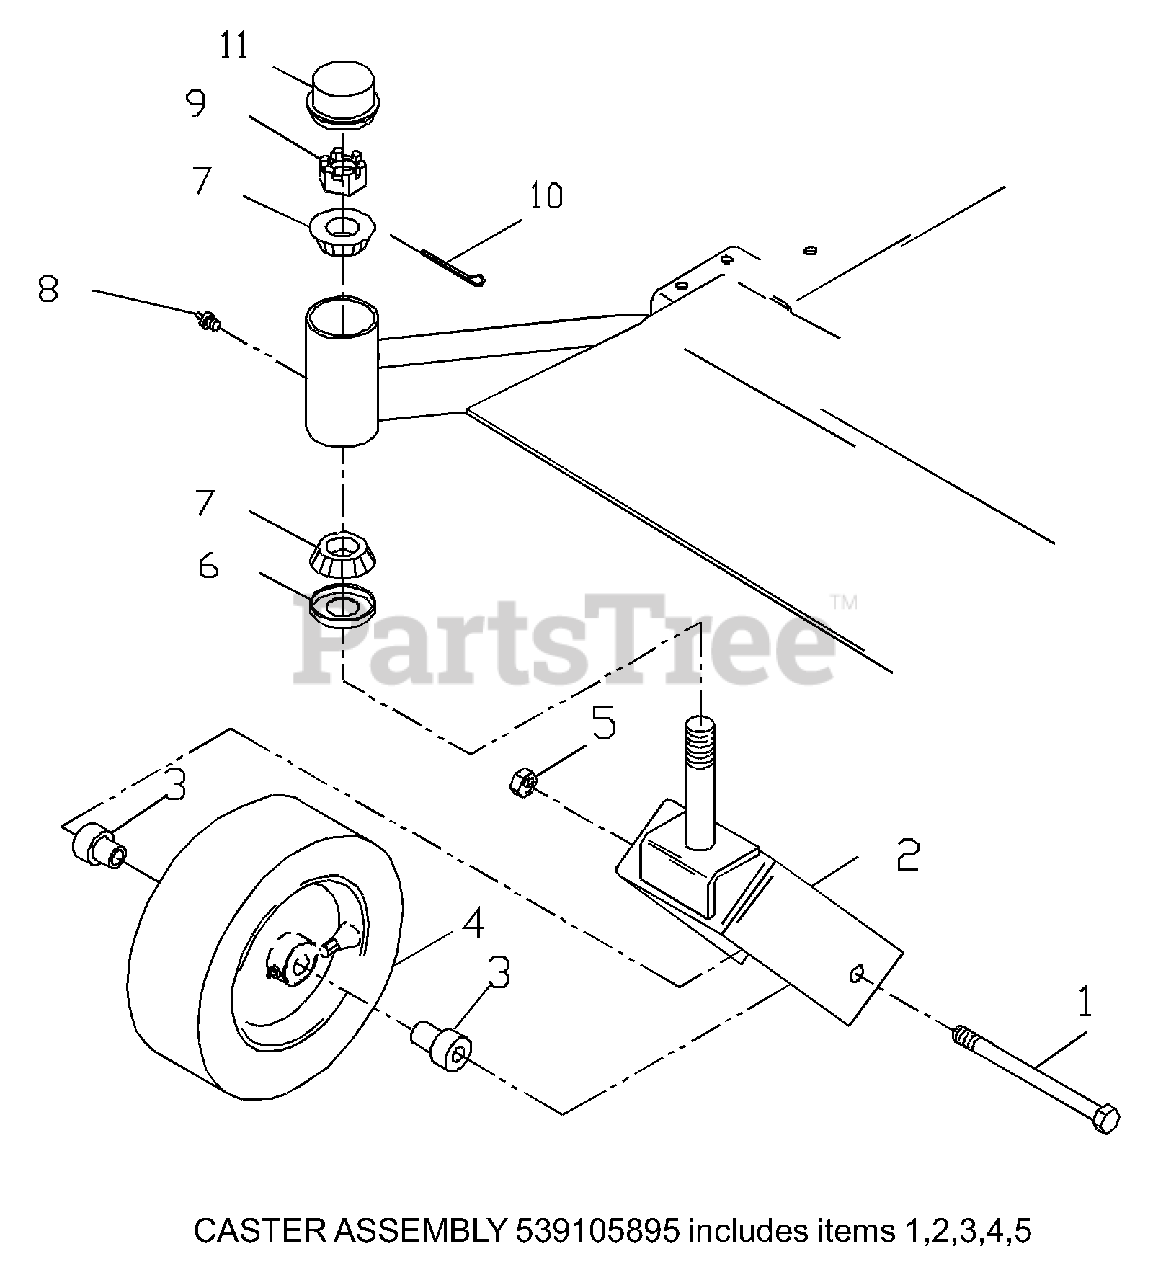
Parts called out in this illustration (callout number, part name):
1	HCS 1/2 X 9.5
2	CASTER YOKE
3	AXLE SPACER
4	TAPERED BEARING
5	NUT 1/2 NYLOC
7	BEARING W/CUP
9	NUT 1.0 CASTLE
10	COTTER PIN 1/8 X 2
11	GREASE CAP
539105895	CASTER ASSEMBLY
